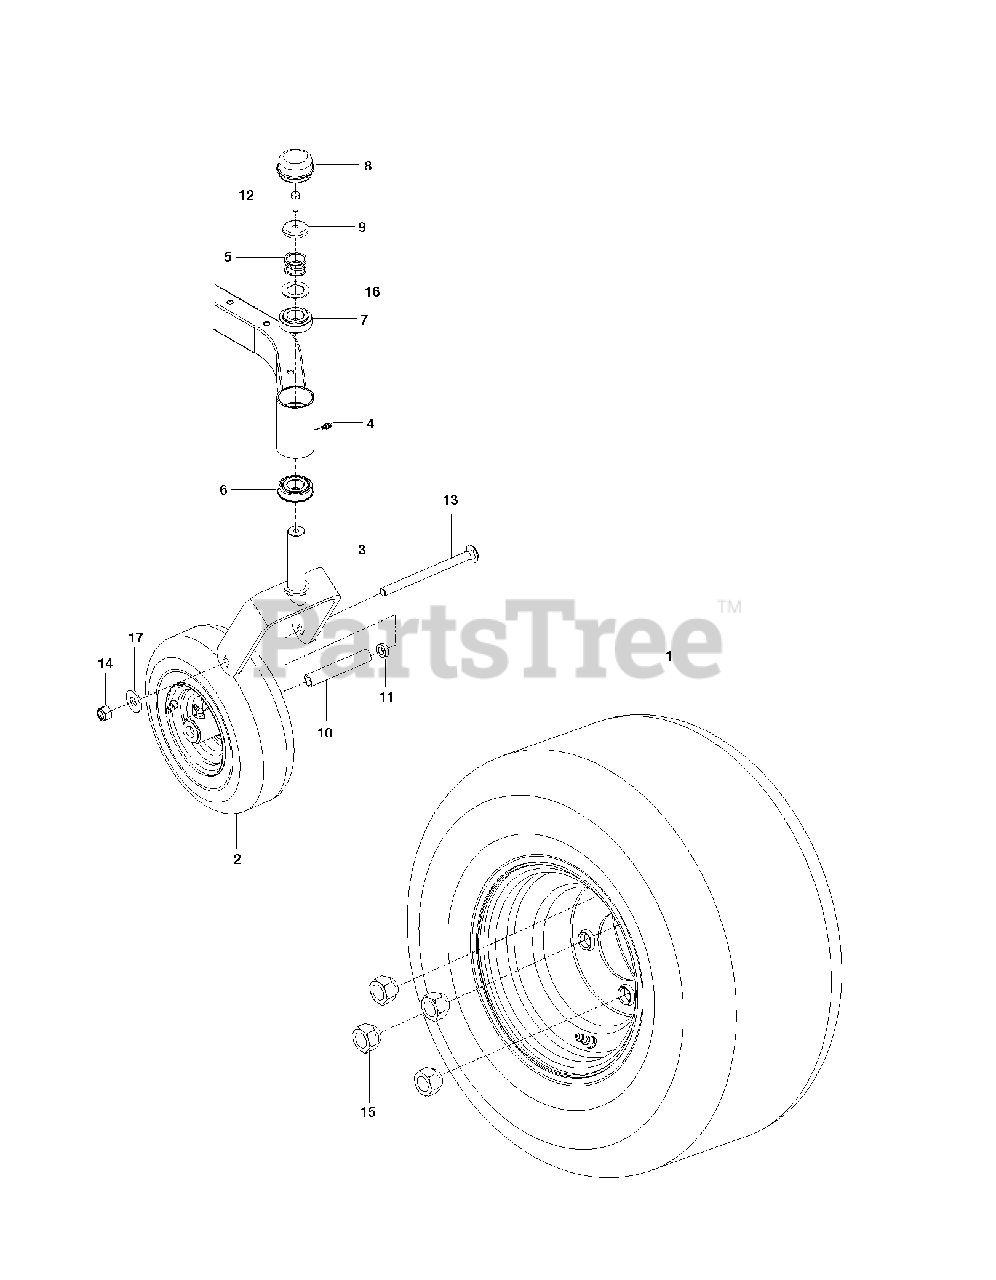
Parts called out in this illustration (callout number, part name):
1	WHEEL.ASSEM.18X8.5-8.KENDA.ZTR
2	WHEEL.11X4-5.K404LG.5X3W/4.188
3	YOKE.CASTER.ORANGE
4	ZERK, 3/16, DRIVE IN
5	SPRING, CASTER
6	BEARING FLANGED
7	BUSHING, CASTER
8	GREASE CAP
9	CASTER.PLUG
11	SPACER, 5/16"
12	5/16-18X1 HHB G5W/NY
13	RHSNB 1/2-13 X 6.50 GR2 ZD
14	NUT 1/2-13 HEX CNTRLK GR 5 ZD
15	LUG NUT 1/2F
16	WASHER, 1.025 ID X 1.64
17	WASHER.9/16 X 1 3/8 X 12 GA.
